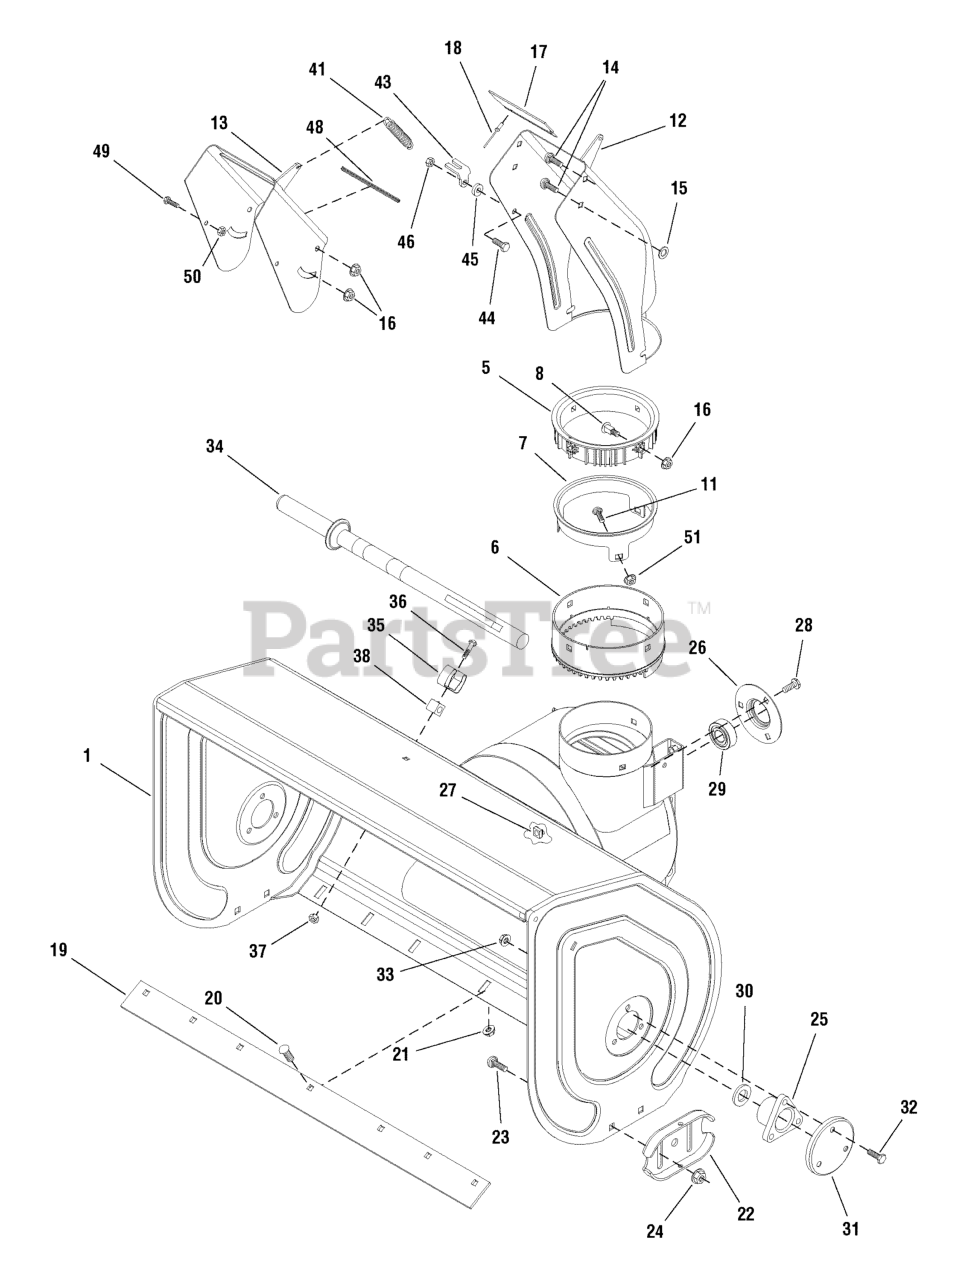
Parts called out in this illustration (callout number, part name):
1	HOUSING ASSEMBLY, 26"
1	HOUSING ASSEMBLY, 28"
5	RING, Retainer, Inner
6	RING, Outer Chute
7	ADAPTER, Chute Ring 14GA
8	CARRIAGE BOLT, 5/16-18 x 1
11	CARRIAGE BOLT, 5/16-18 x 5/8 G5
12	CHUTE & BRACKET ASSEMBLY, Lower
13	CHUTE ASSEMBLY
14	CARRIAGE BOLT, 5/16-18 x 3/4 G5
16	NUT, Hex Flange ESNA, 5/16-18
17	FLAP, Chute Insert
18	RIVET, Pop
19	BLADE, Scraper for 28"
19	BLADE, Scraper 26"
20	CARRIAGE BOLT, 5/16-18 x 5/8 G5
21	NUT, Hex Flange Two-Way Lock, 5/16-18
22	SKID, Shoe Reversible
23	CARRIAGE BOLT, 3/8-16 x 3/4 G5
24	NUT, Hex Flange ESNA, 3/8-16
25	BEARING, Flange
26	BEARING, Retainer
27	RETAINER, Nut, 5/16-18
28	SCREW, Hex Whiz Lock Flange, 5/16-18 x 3/4
29	BEARING, Greased
31	CAP, Bearing
32	CAPSCREW, Hex Head, 5/16-18 x 7/8 G5
33	NUT, Hex Flange Whiz Lock, 5/16-18
34	STICK, Cleanout w/Brush
35	CLIP, Retainer
36	SCREW, Hex Washer Head Slot
37	NUT, Hex Lock 10-24 with Nylon Insert
38	BLOCK, Universal Pivot
41	SPRING, Extension
43	BRACKET, Remote Chute
44	CAPSCREW, Hex Head, 5/16-18 x 3/4 G5
46	NUT, Hex Centerlock, 5/16-18
48	EDGING, with Adhesive
49	BOLT, Shroud 1/4 x 5/16-1/4
50	NUT, Hex Flange Centerlock, 1/4-20
51	NUT, Hex Keps Conical Washer, 5/16-18
